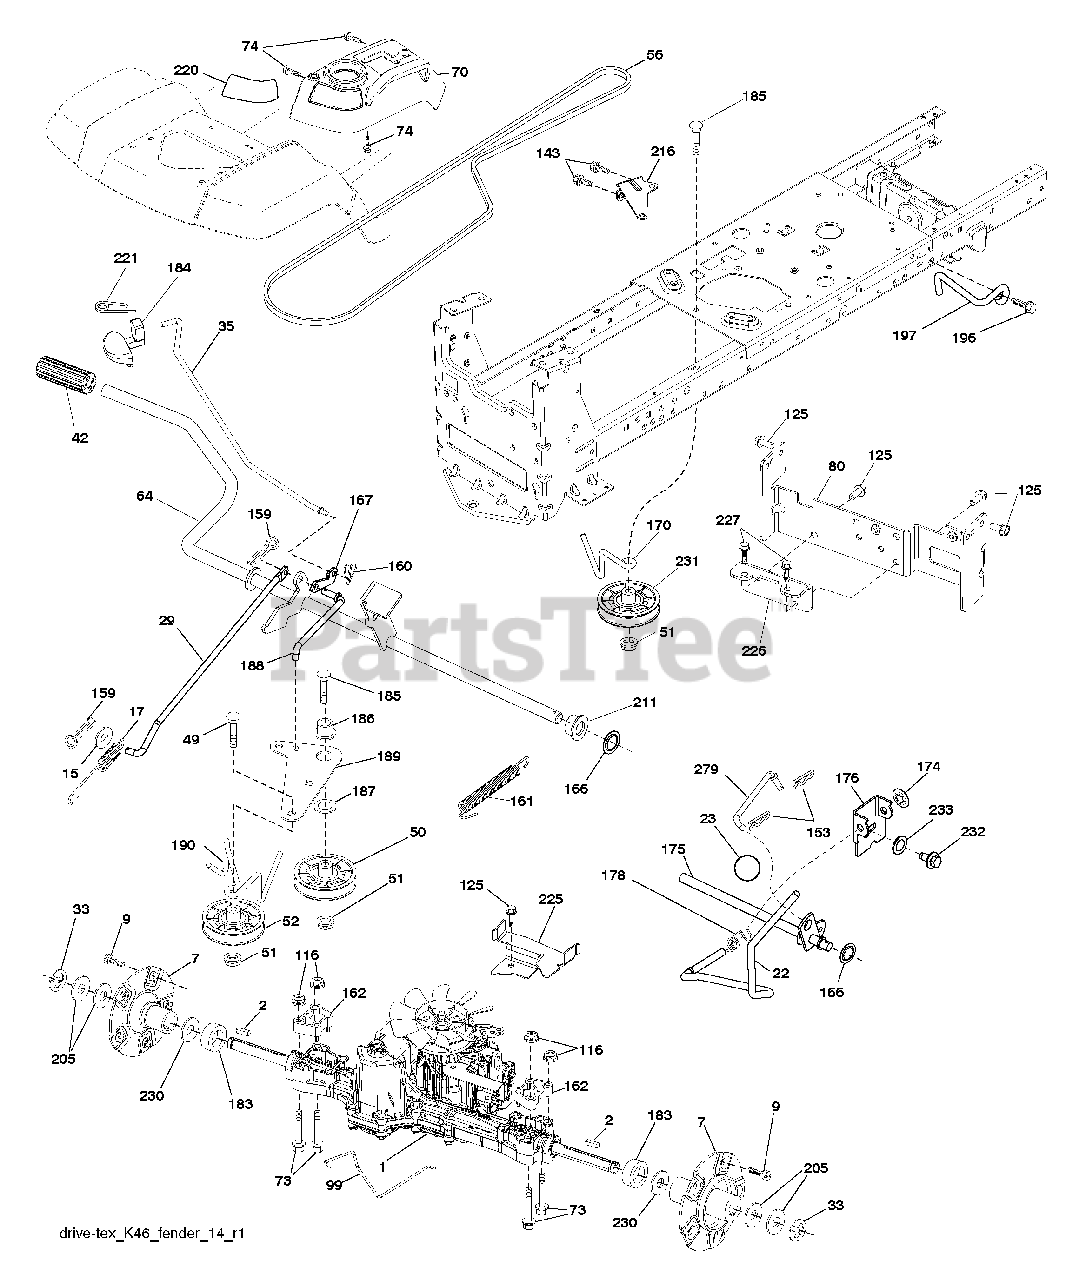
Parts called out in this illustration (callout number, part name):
1	Transaxle, TUFFTORQ K46 AW
7	Hub Asm. Wheel Rear 22" TX GT .06
9	Bolt Hub Wheel Rear
15	Washer 13/32 x 13/16 x 16 Ga.
17	Spring Brake
29	Rod, Brake
35	Rod Brake Park
42	Cover Foot Pedal
50	Pulley Idler Flat
51	Lock Nut 3/8-16
52	Idler V-Groove 910" Offset
56	V-Belt Drive
64	Shaft Asm. Pedal Brake Control
70	Console Asm.
73	Bolt Hex Flghd 5/16-18 x 3.75
74	Screw 1/4 x 1/2
80	Strap Torque
99	Rod Bypass
116	Nut Lock Hex Flange 5/16-18
125	Screw 5/16-18 x 3/4
143	Screw 5/16-18 x 1/2
153	Retainer Spring
159	Pin Cotter 1/8 x 3/4
160	Retainer Clip
161	Spring Return Clutch
162	Spacer Transaxle 18 and 22
167	Latch Brake Parking
170	Keeper Belt Centerspan
175	Shaft Asm Shift
176	Arm Clevis Rod Shift
178	Spring Shift
183	Spacer Split
184	Handle Parking Brake
185	Bolt Rdhd Sqnk 3/8-16 x 2-3/4 Gr. 5
186	Spacer Retainer
187	Washer
188	Link Clutch Ground Drive
189	Bellcrank Ground Drive
190	Keeper Bellcrank Ground Drive
196	Screw 3/8-16 x 1
197	Link Clutch Anti-Rotation
211	Bushing Brake Shaft
216	Bracket Pulley Idler
220	Reflector RH
221	Retainer Spring Clip Handle
225	Keeper Belt Trans.
226	Bracket Mount Torque
227	Screw 5/16-18 x 3/4
230	Washer Hardened
231	Idler V-Groove 1.688" Offset
232	Bolt 7/16-14 x 1 Gr. 5
233	Washer Serrated
279	Link Shift
